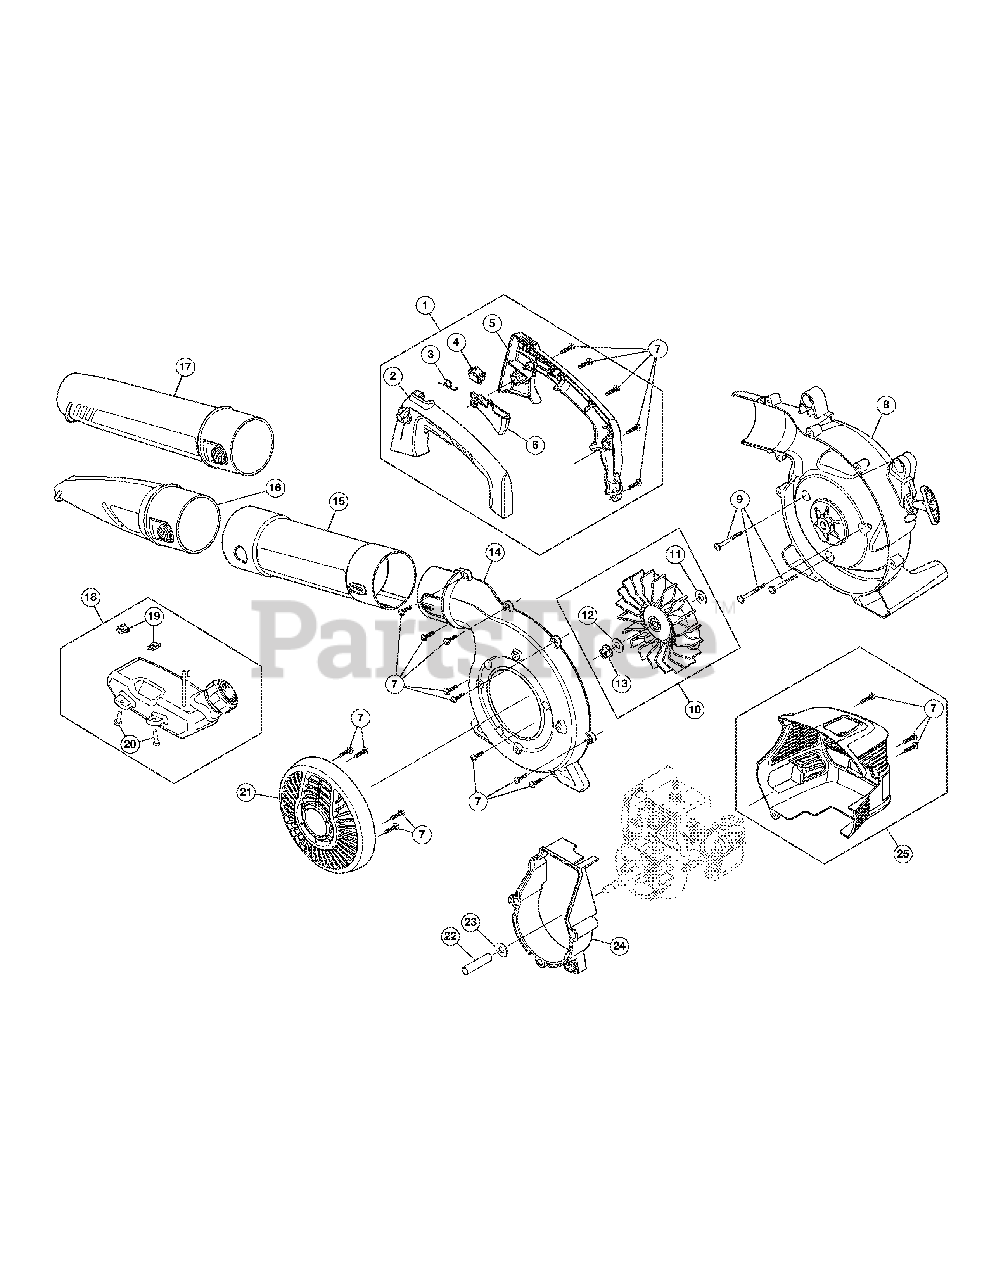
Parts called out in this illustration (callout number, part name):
1	Handle Assembly
2	Handle (LH)
3	Trigger Spring
4	On/Off Switch
6	Throttle Trigger
8	Impeller Housing Assembly (RH) (Incl. 9)
10	Impeller Assembly
12	Lock Washer
14	Impeller Housing Assembly (LH) (Incl. 7)
15	Upper Blower Tube
16	Blower Nozzle
17	Lower Blower Tube
18	Fuel Tank Assembly
19	U-Shaped Nut
21	Intake Cover (Incl. 7)
22	Shaft Spacer
24	Engine Adapter (Incl. 9)
25	Engine Cover Housing (Incl. 7)
